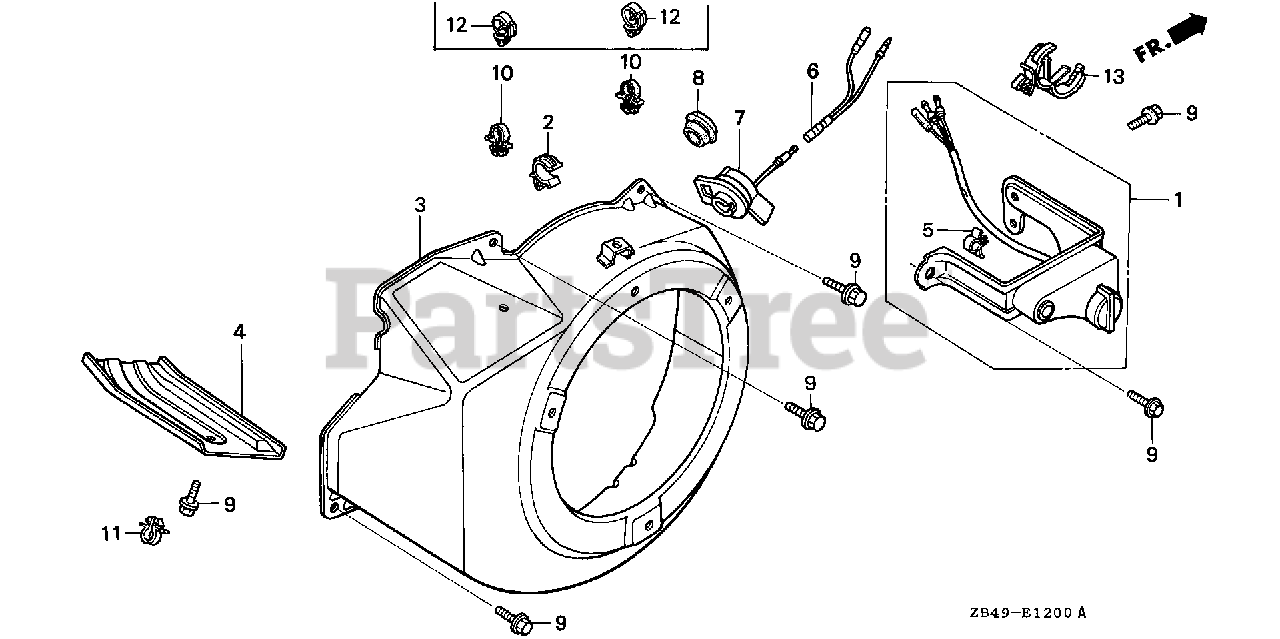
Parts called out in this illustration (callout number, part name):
2	CLIP, TUBE
3	COVER, FAN *NH1* (BLACK)
7	SWITCH ASSY., ENGINE STOP
9	BOLT, FLANGE (6X12) (CT200)
13	CLIP, HARNESS
